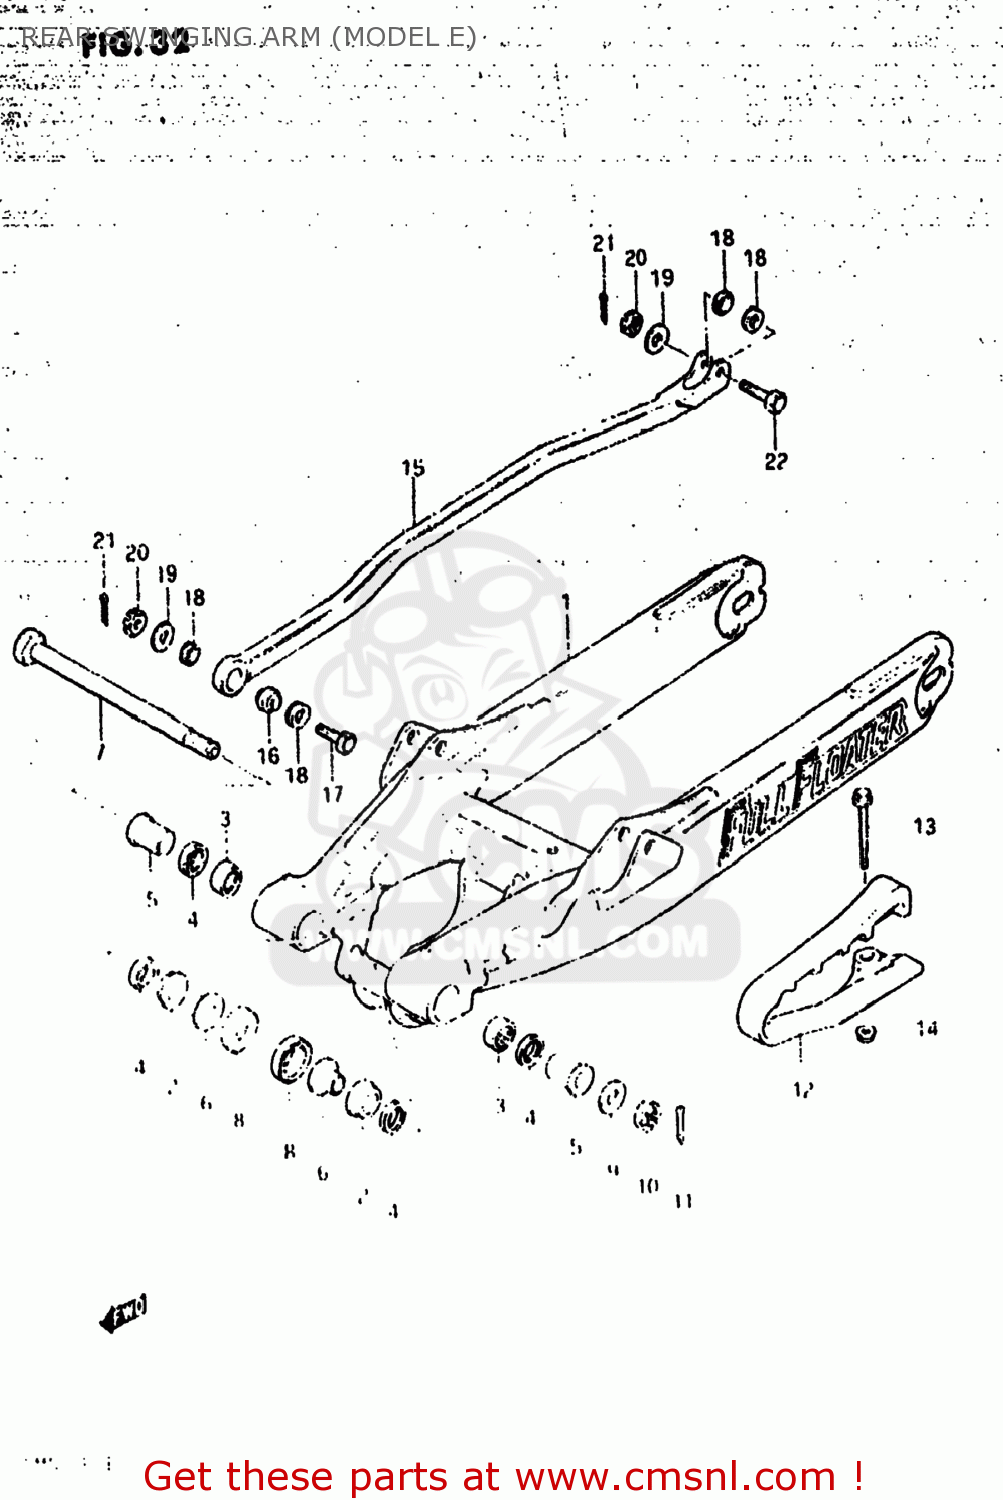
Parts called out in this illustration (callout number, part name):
1	SWING ARM ASSEMBLY,REAR
2	BUSHING,REAR SWING ARM PIVOT
3	BEARING(20X27X20)
4	OIL SEAL
5	SPACER,RR SWGARM PIVOT
6	SPACER,RR SWGARM PIVOT INNER
7	SHAFT,RR SWINGINGARM PIVOT
8	COVER,RR SWGARM DUST SEAL
9	WASHER(14.5X29X2.3)
10	NUT
11	COTTER PIN
12	BUFFER,CHAIN TOUCH DEFLECTOR
13	BOLT 6X65
14	NUT
15	LINK,REAR TORQUE
16	SPHERICAL BEARING,TORQUE
17	BOLT 8X28
18	19
19	WASHER
20	NUT 8MM
21	PIN 20X20
22	BOLT 8X29.5
